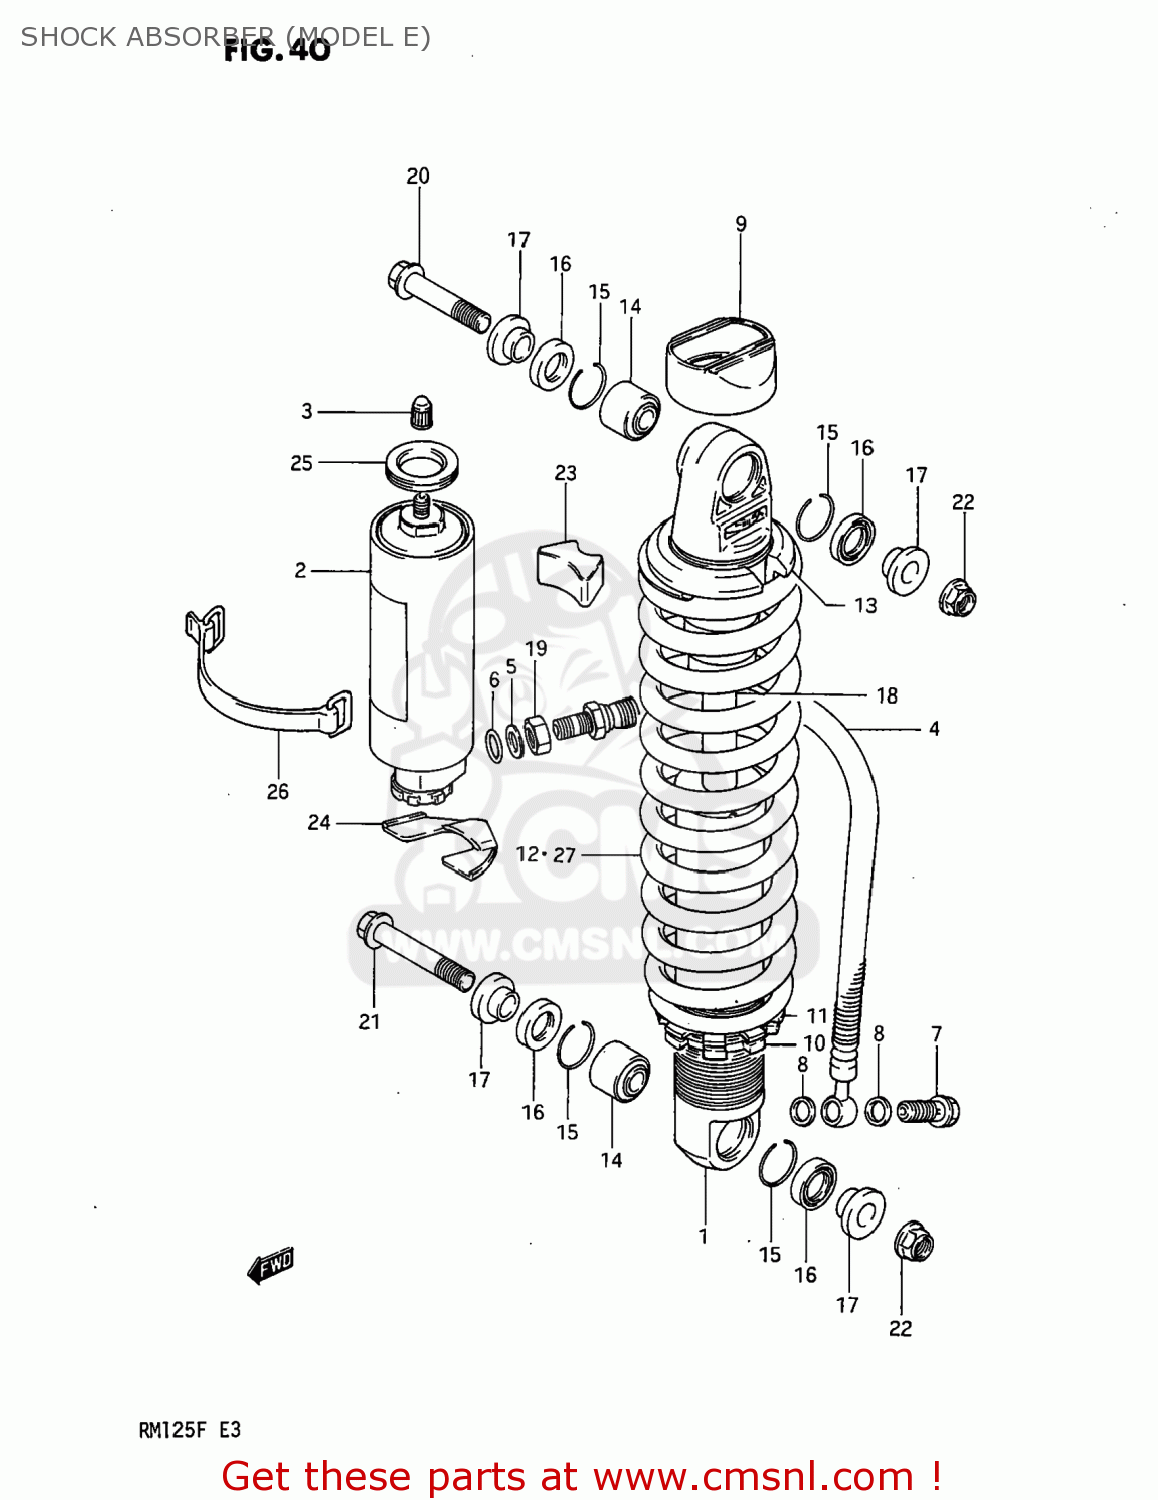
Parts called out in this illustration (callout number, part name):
1	ABSORBER ASSEMBLY,REAR SHOCK
2	RESERVE TANK,REAR SHOCK
3	CAP
4	HOSE,REAR SHOCK ABSORBER
5	WASHER,REAR SHOCK HOSE
6	O-RING,RESERVE TANK
7	BOLT,REAR SHOCK ABSORBER
8	GASKET (NAS)
9	CLIP
10	GUIDE,REAR SHOCK ABSORBER SPRING
11	GUIDE,SPRING
12	SPRING
13	GUIDE,REAR SHOCK ABSORBER SPRING
14	BEARING,REAR SHOCK ABSORBER
15	RING
16	SEAL,DUST
17	SPACER
18	ROD,PISTON
19	NUT 12MM
20	BOLT,REAR SHOCK ABSORBER
21	BOLT(10X52)
22	NUT
23	CUSHION,RESERVOIR TANK
24	CUSHION,RESERVOIR TANK
25	CUSHION,RESERVOIR TANK
26	BAND
27	SPRING
